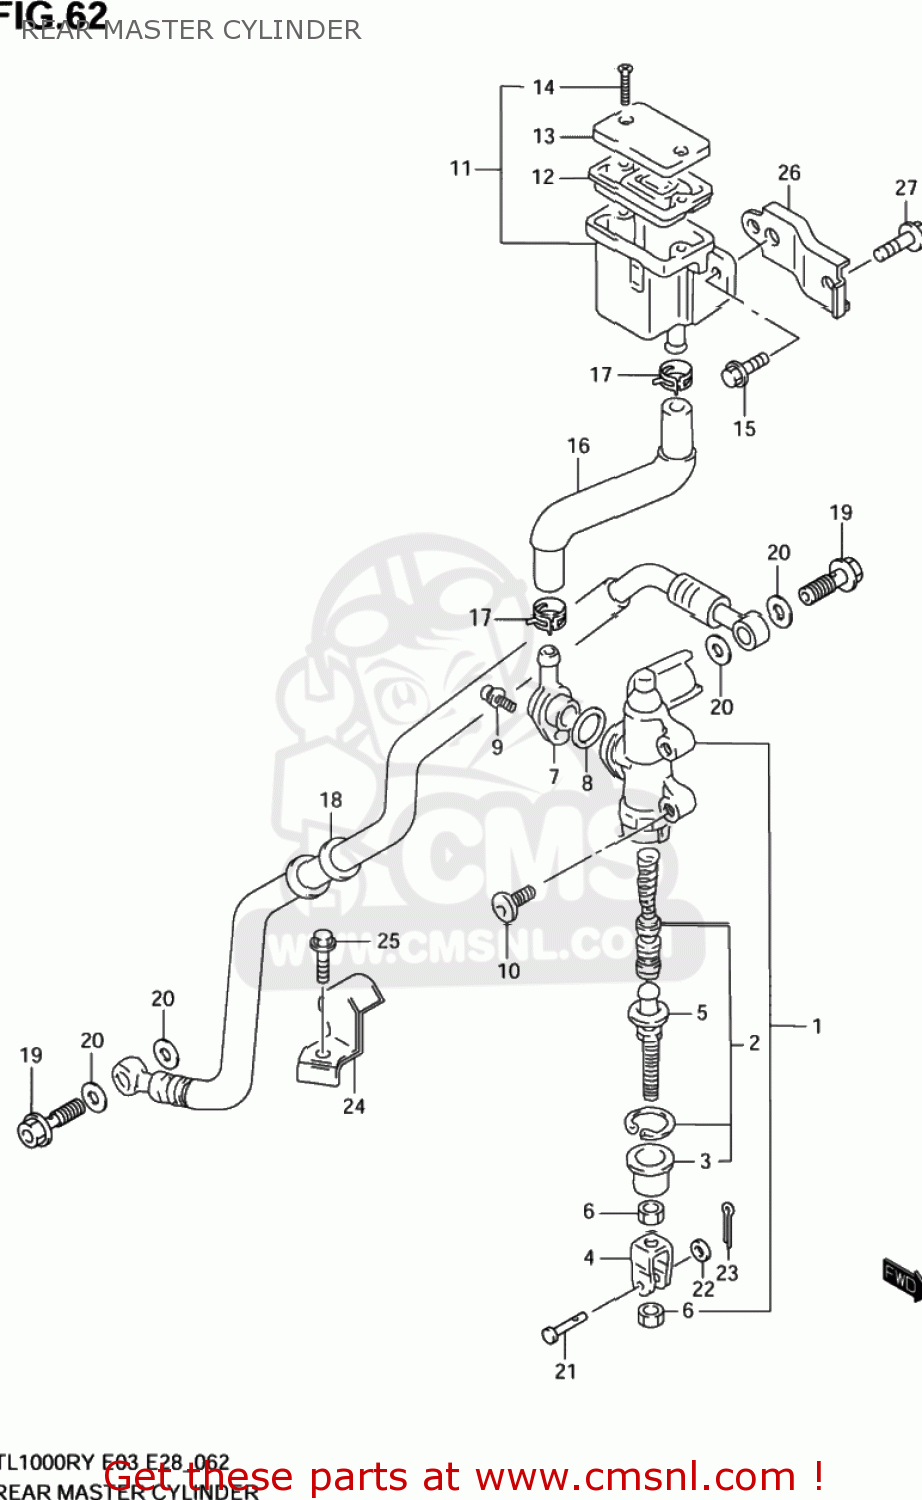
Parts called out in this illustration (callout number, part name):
1	CYLINDER ASSY,RR MASTER
2	PISTON/CUP SET
3	BOOT
4	YOKE
5	ROD,PUSH
6	NUT
7	CONNECTOR
8	O RING
9	SCREW
10	SCREW(6X25)
11	TANK ASSY,RR RESERVOIR
12	DIAPHRAGM
13	CAP
14	SCREW
15	BOLT
16	HOSE,RESERVOIR TANK
17	CLIP
18	HOSE,RR BRAKE
19	BOLT UNION
20	WASHER(10X15X1.5)
21	PIN
22	WASHER
23	PIN
24	CLAMP,RR BRAKE HOSE
25	BOLT
26	BRACKET,RR RESERVOIR TANK
27	BOLT
